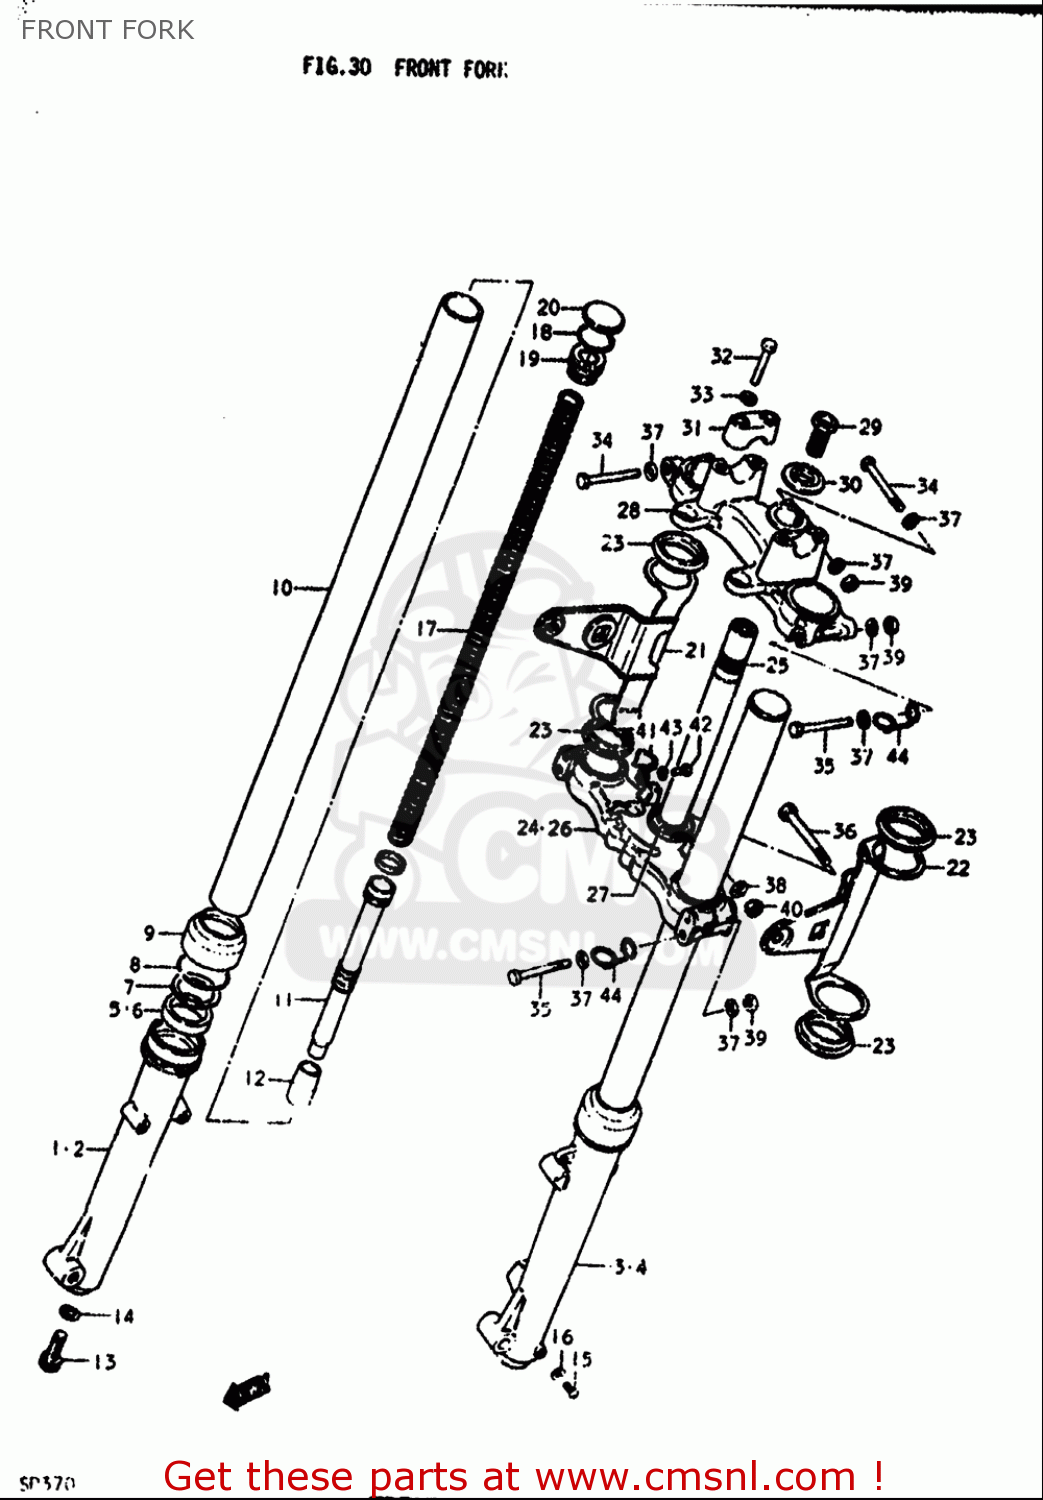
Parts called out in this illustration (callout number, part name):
5	SEAL,OIL
6	SEAL,OIL
9	SEAL,DUST
12	PIECE,OIL LOCK
13	BOLT,FORK CYLINDER(10X25)
14	GASKET (NAS)
15	SCREW
16	GASKET,DRAIN,PLUG (NAS)
18	O RING
19	CAP,FORK INNER TUBE
20	CAP,FR FORK
27	RACE,STEERING OUTER LWR
29	BOLT,STEERING STEM HEAD
30	WASHER
31	HOLDER,HANDLEBAR
32	BOLT
33	WASHER,LOCK
34	BOLT
35	BOLT
36	BOLT
37	WASHER
38	WASHER,LOCK
39	NUT
40	NUT
41	CLIP,BRAKE CABLE
42	SCREW
43	WASHER,LOCK
44	CLIP
